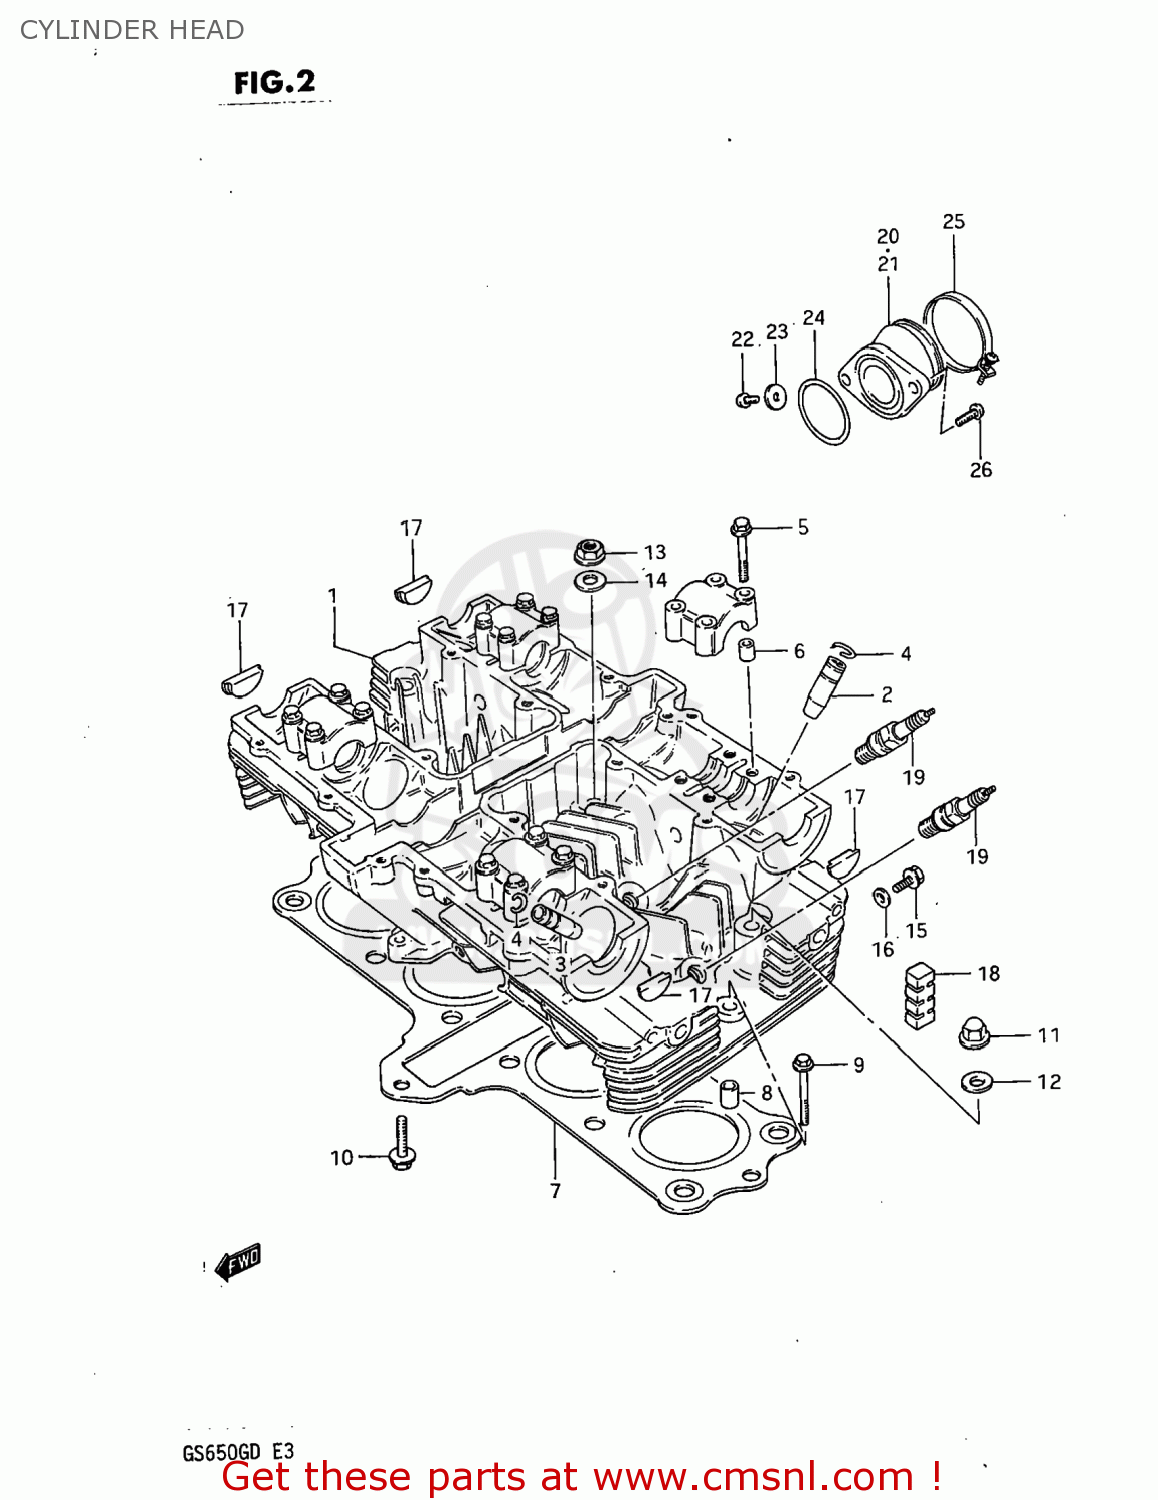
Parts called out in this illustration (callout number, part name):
1	HEAD,CYLINDER
2	GUIDE,INTAKE VALVE
3	GUIDE,EXHAUST VALVE
4	RING,SNAP
5	BOLT(6X39)
6	PIN(6.2X8X11)
7	GASKET,CYLINDER HEAD (MCA)
8	PIN
9	BOLT,UNDER
10	BOLT
11	NUT
12	GASKET (NAS)
13	NUT
14	WASHER(8.5X19X2.3)
15	BOLT
16	GASKET (NAS)
17	PLUG
18	PAD,CYLINDER
19	SPARK PLUG D8EA
20	PIPE,INTAKE,R
21	PIPE,INTAKE,L
22	BOLT
23	WASHER
24	O-RING
25	CLAMP
26	SCREW
